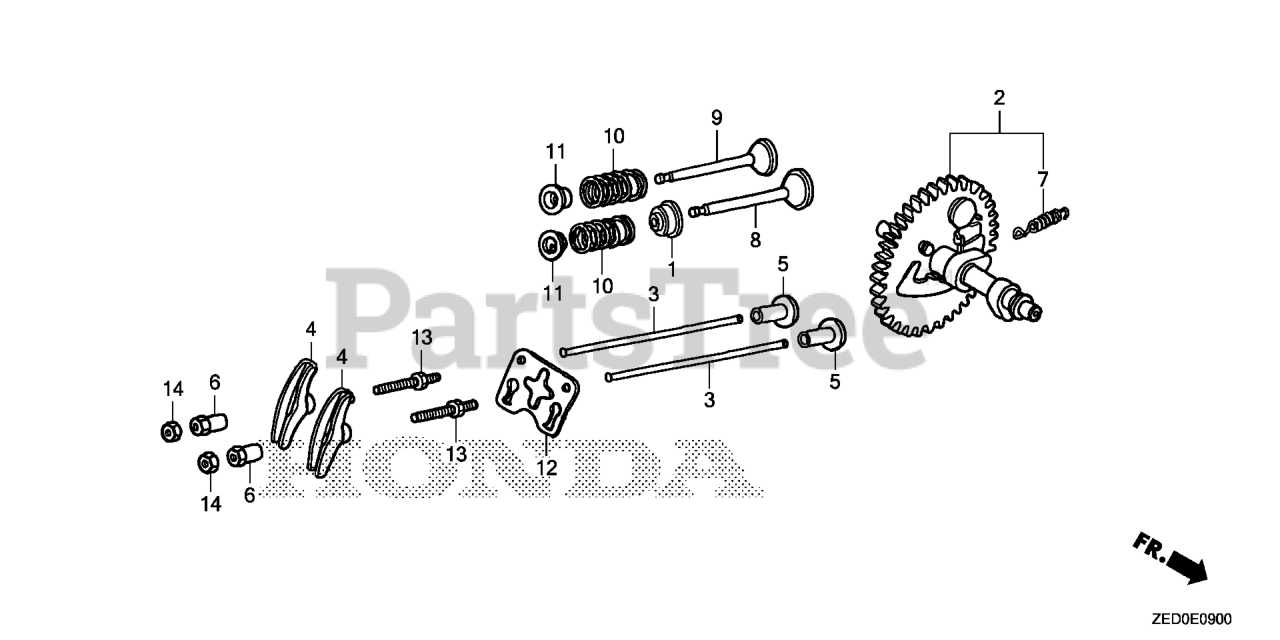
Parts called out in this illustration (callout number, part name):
1	SEAL, VALVE STEM
2	CAMSHAFT ASSY.
4	ARM, VALVE ROCKER
5	LIFTER, VALVE
6	PIVOT, ROCKER ARM
7	SPRING, WEIGHT RETURN
8	VALVE, IN.
9	VALVE, EX.
10	SPRING, VALVE
11	RETAINER, VALVE SPRING (EXHAUST SIDE)
11	RETAINER, VALVE SPRING
12	PLATE, PUSH ROD GUIDE
13	BOLT, PIVOT (8MM)
14	NUT, PIVOT ADJ.
